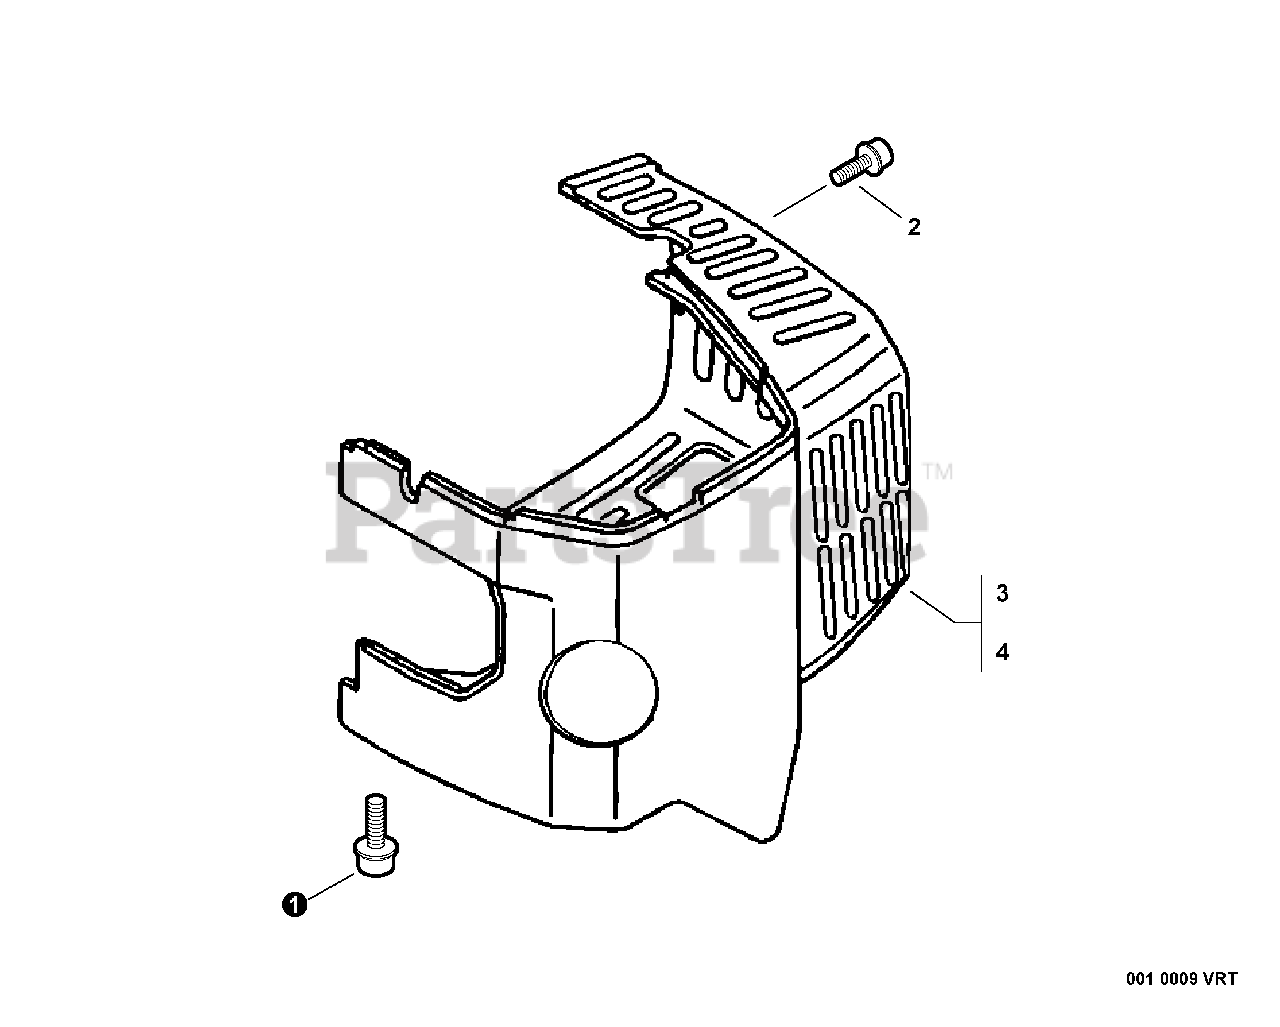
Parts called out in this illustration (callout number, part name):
1	SCREW - 4X20
2	SCREW - 4X8
3	COVER, ENGINE - GRAY
4	COVER, ENGINE - ORANGE
